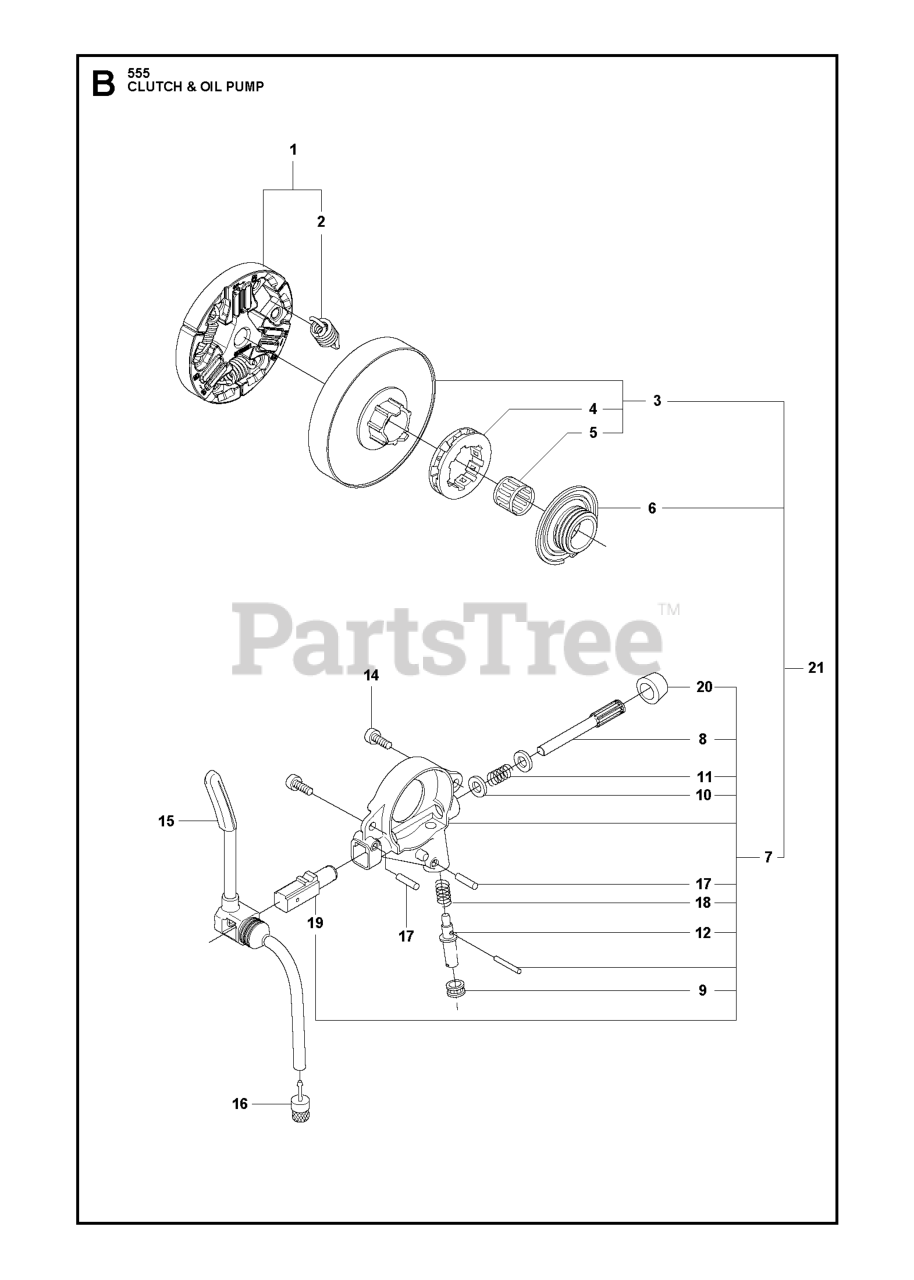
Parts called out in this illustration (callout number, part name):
2	CLUTCH SPRING
3	CLUTCHES
3	CLUTCH DRUM 3/8" 7T
3	CLUTCH DRUM ASSY RIM .325"7T
4	RIM SPROCKET 7T .325
4	68210 RIMSPROCKET
5	SUPPORT BUSHING
6	WORM WHEELS
6	WORM WHEEL
8	PUMP PISTON
12	ADJUSTING SCREW
14	SCREW ITXSCM M4X15 T27 12.9 T
16	OIL PLUMMET
19	PUMP CYLINDER
20	SEALING PLUG
21	CLUTCHES
